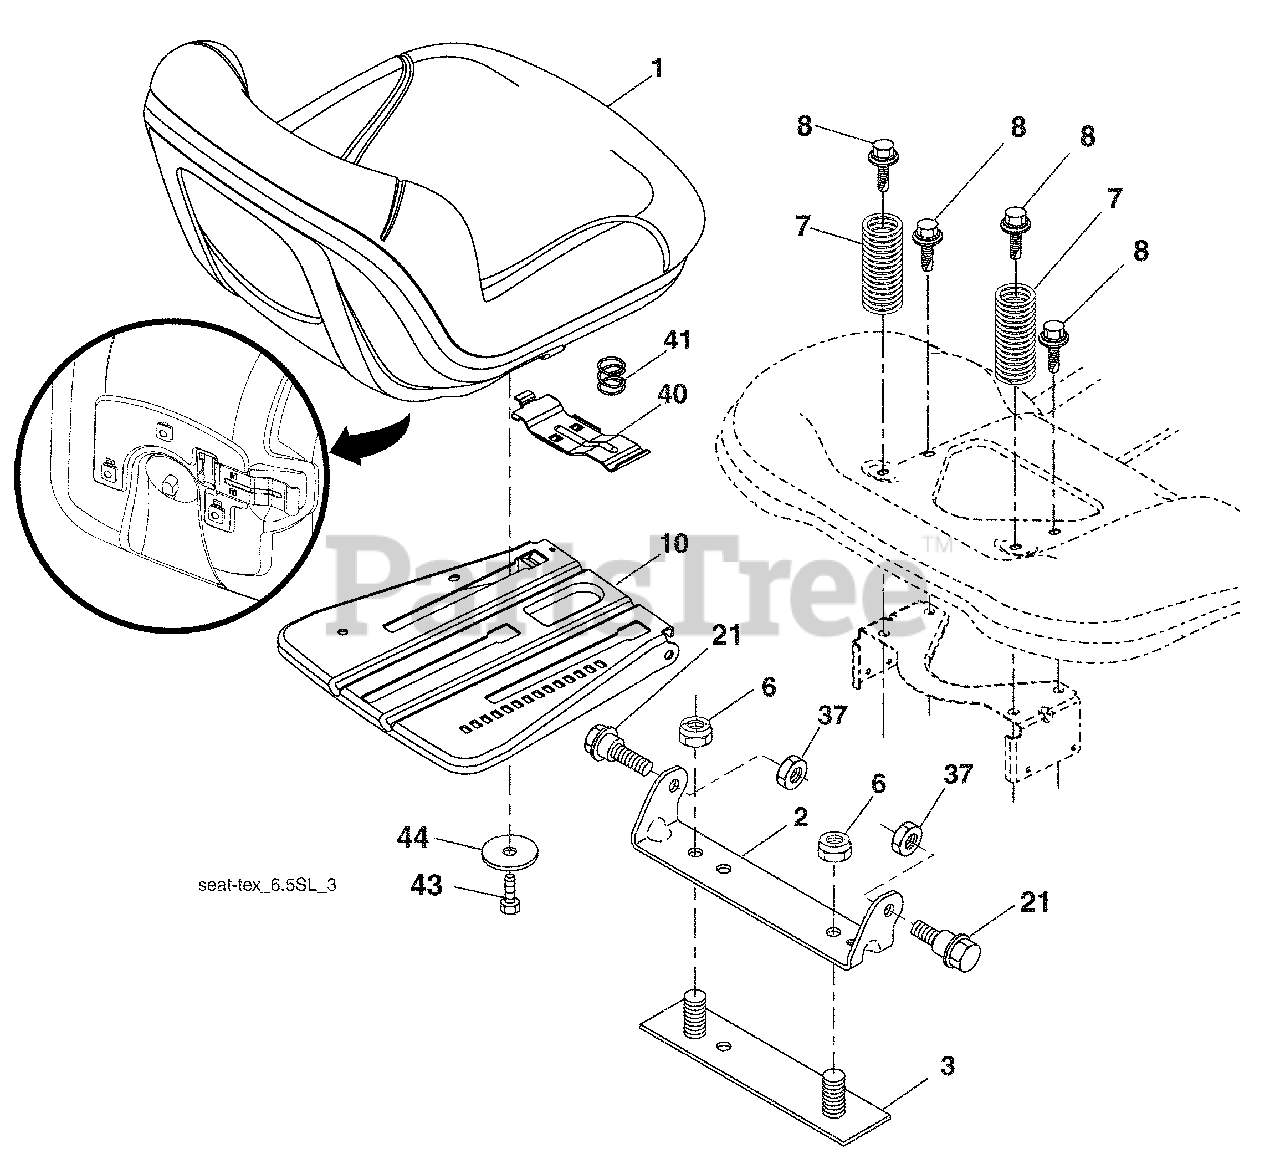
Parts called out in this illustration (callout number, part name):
1	Seat
2	Bracket Pivot Fender
3	Strap, Asm Fender
6	Nut, Lock w/Ins. 3/8-16 unc
7	Spring, Seat Cprsn
8	Bolt 5/16-18 unc x 3/4 w/Sems
10	Pan, Seat
21	Bolt, Shoulder 5/16-18
37	Nut, Lock 5/16-18 unc
40	Handle Slide Seat
41	Spring Latch Seat
43	Bolt Fin Hex 3/8-16 unc x 3/4
44	Washer 13/32 x 2-3/8 x 12 Ga.
